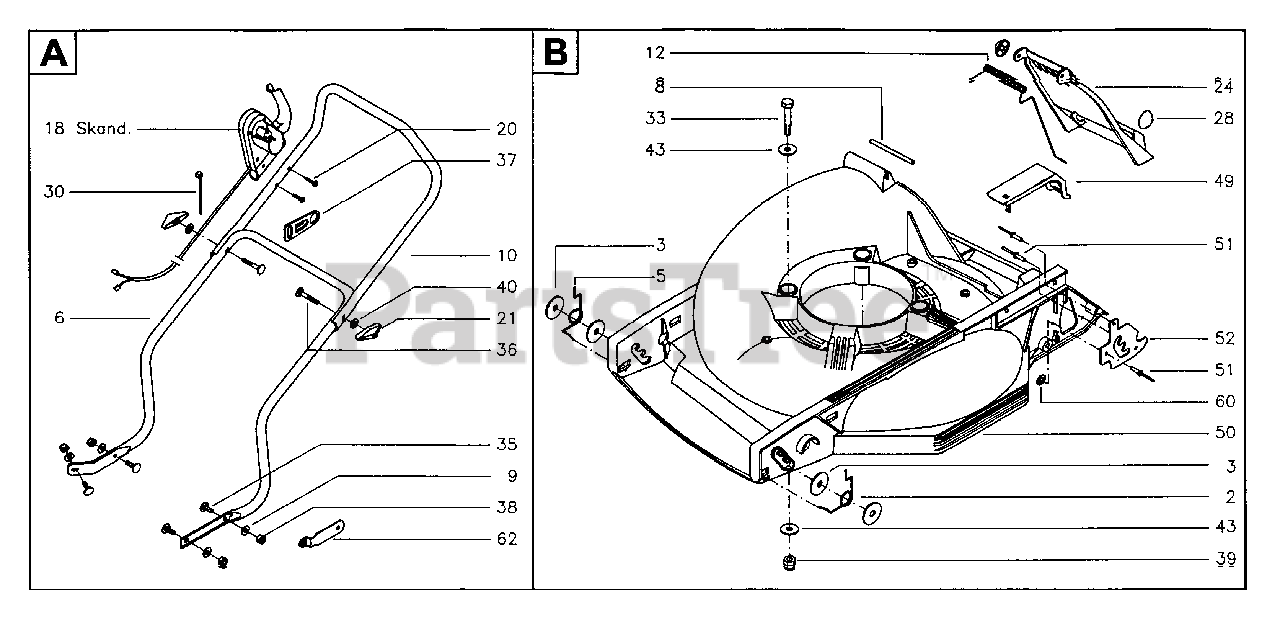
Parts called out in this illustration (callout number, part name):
38	LOCKNUT M6
39	LOCKNUT M8
40	WASHER - 15X7.3X1.6
60	WASHER
